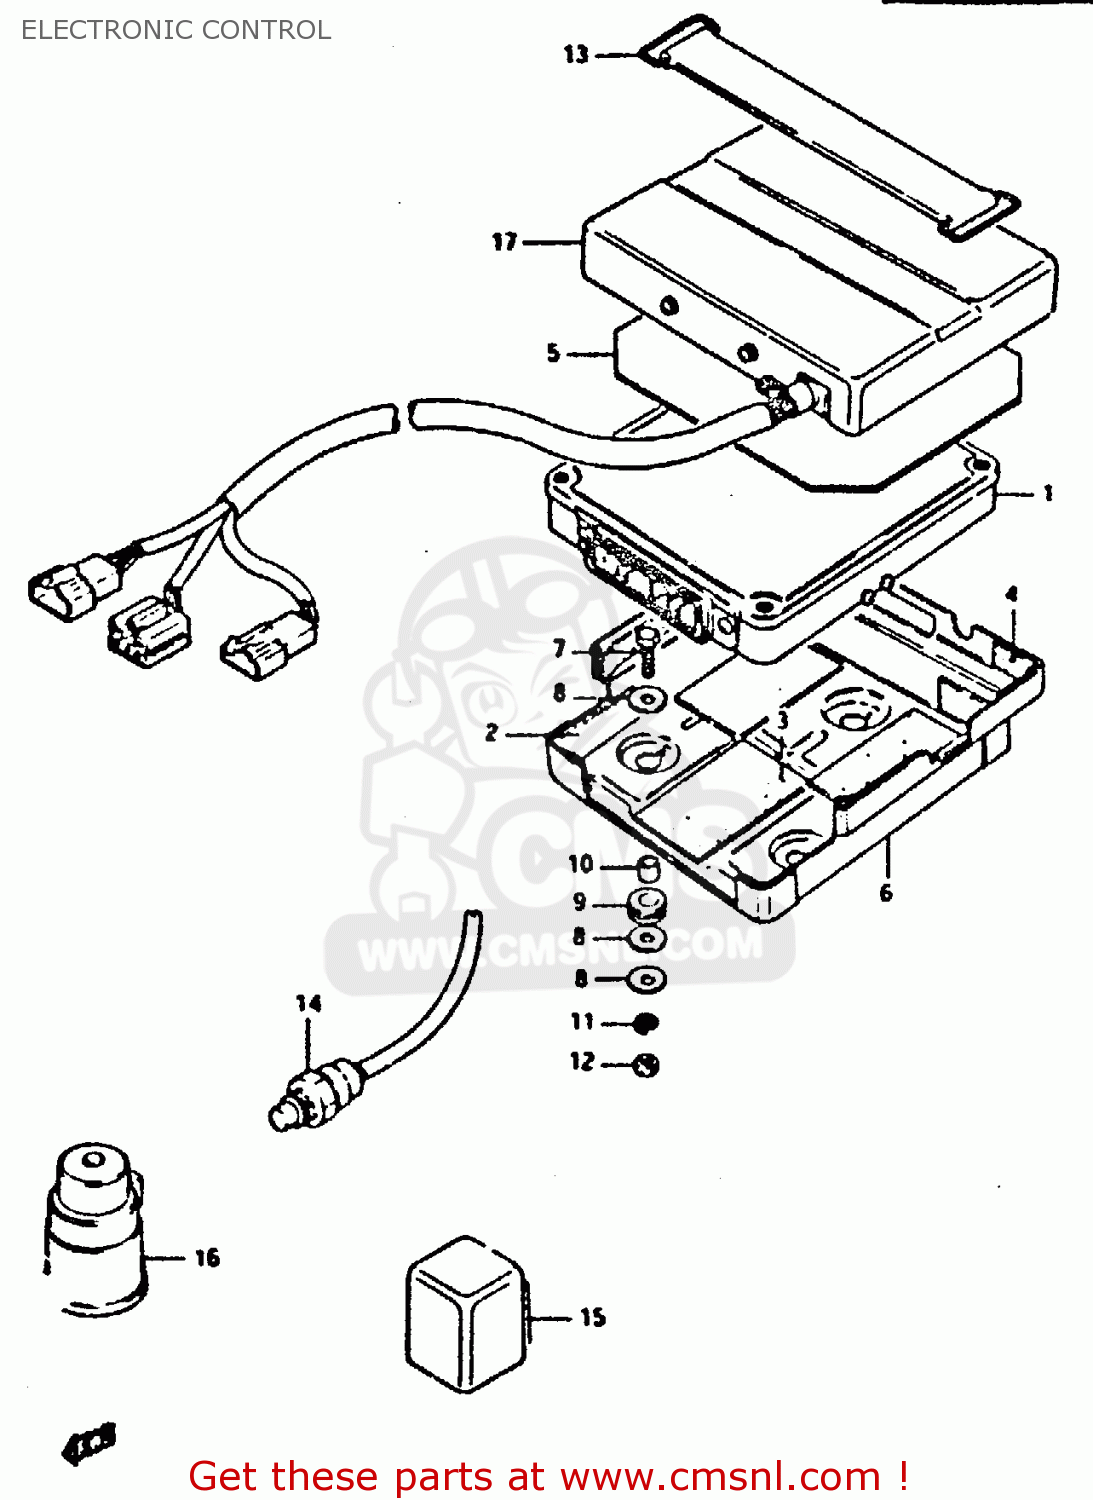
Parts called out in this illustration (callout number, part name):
1	ELECTRONIC CONTROL UNIT
2	PROTECTOR,20X9
3	CUSHION, NO. 2
4	CUSHION, NO. 3
5	CUSHION, NO. 5
6	HOLDER,CONTROL UNIT
7	BOLT
8	WASHER
9	CUSHION
10	SPACER(6.1X9X7.5)
11	LOCK WASHER
12	NUT
13	BAND
14	SENSOR,OVER HEAT WARNING
15	SENSOR,IDLE POSITION
16	CIRCUIT,OPENING RELAY
17	CDI UNIT
